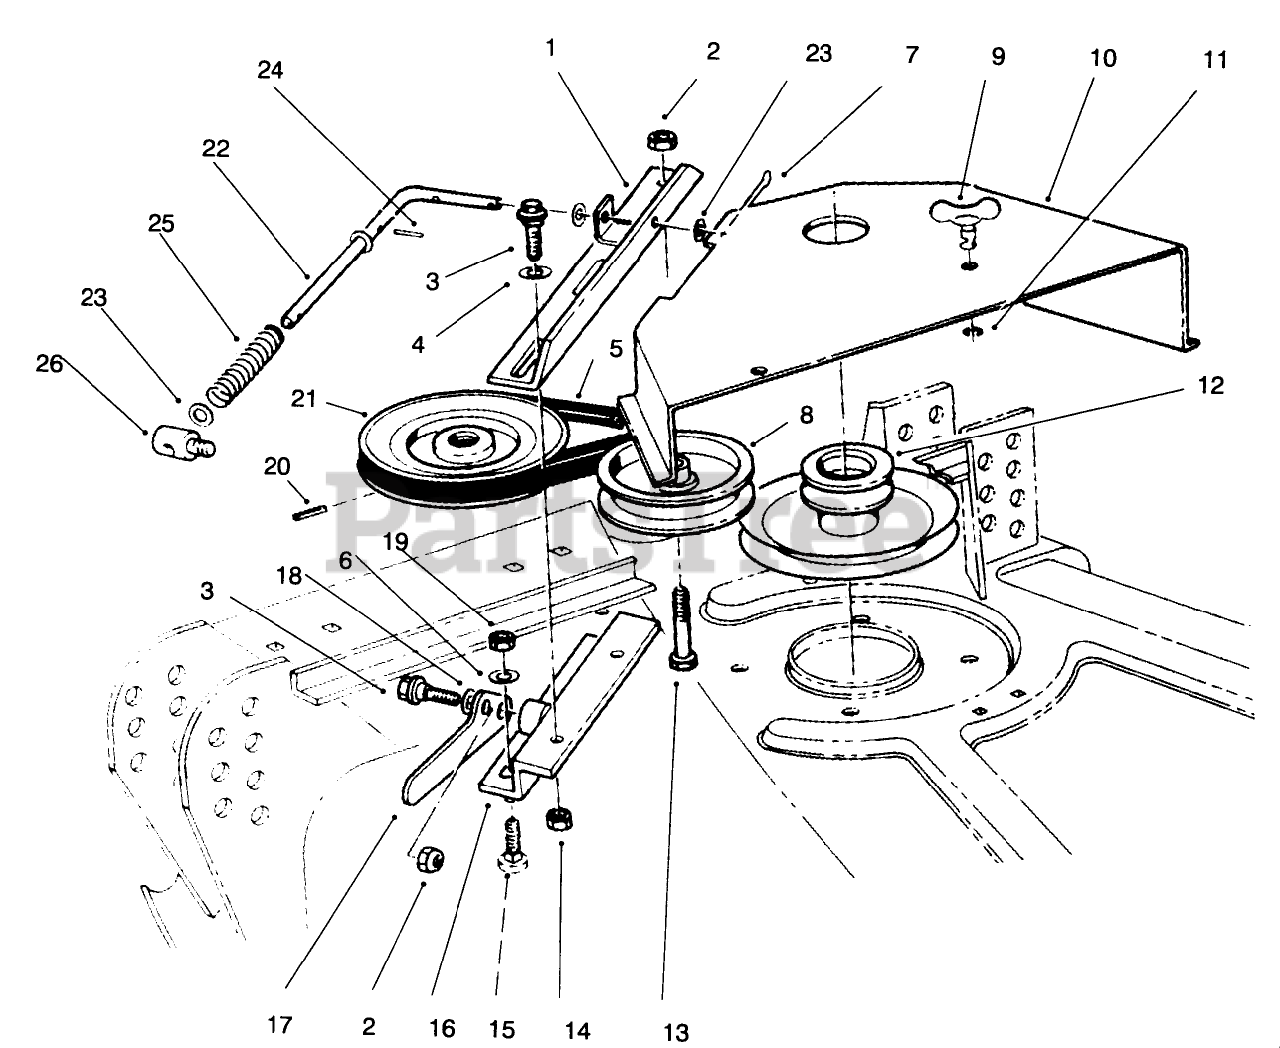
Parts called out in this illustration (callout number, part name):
1	Slide ldler
2	NUT-LOCK, NI
3	SCREW-SHOULDER
4	WASHER-THRUST
5	V-BELT
6	WASHER-PLAIN
7	PIN-COTTER
8	PULLEY-IDLER
9	STUD-HEAD, WING
10	Cover-Deck
11	RING-SNAP
12	DECK PULLEY WA
13	SCREW-HH
14	NUT-LOCK, NI
15	SCREW-CARR
16	Bracket-Idler
17	Lever-Idler
18	WASHER-SPRING
19	NUT-KEPS
20	PIN-ROLL
21	Pulley-Gear Box
22	Rod-Idler
23	WASHER-FLAT
24	PIN-ROLL
25	COMPRESSION SPRING
26	BAGGER TRUNNION
